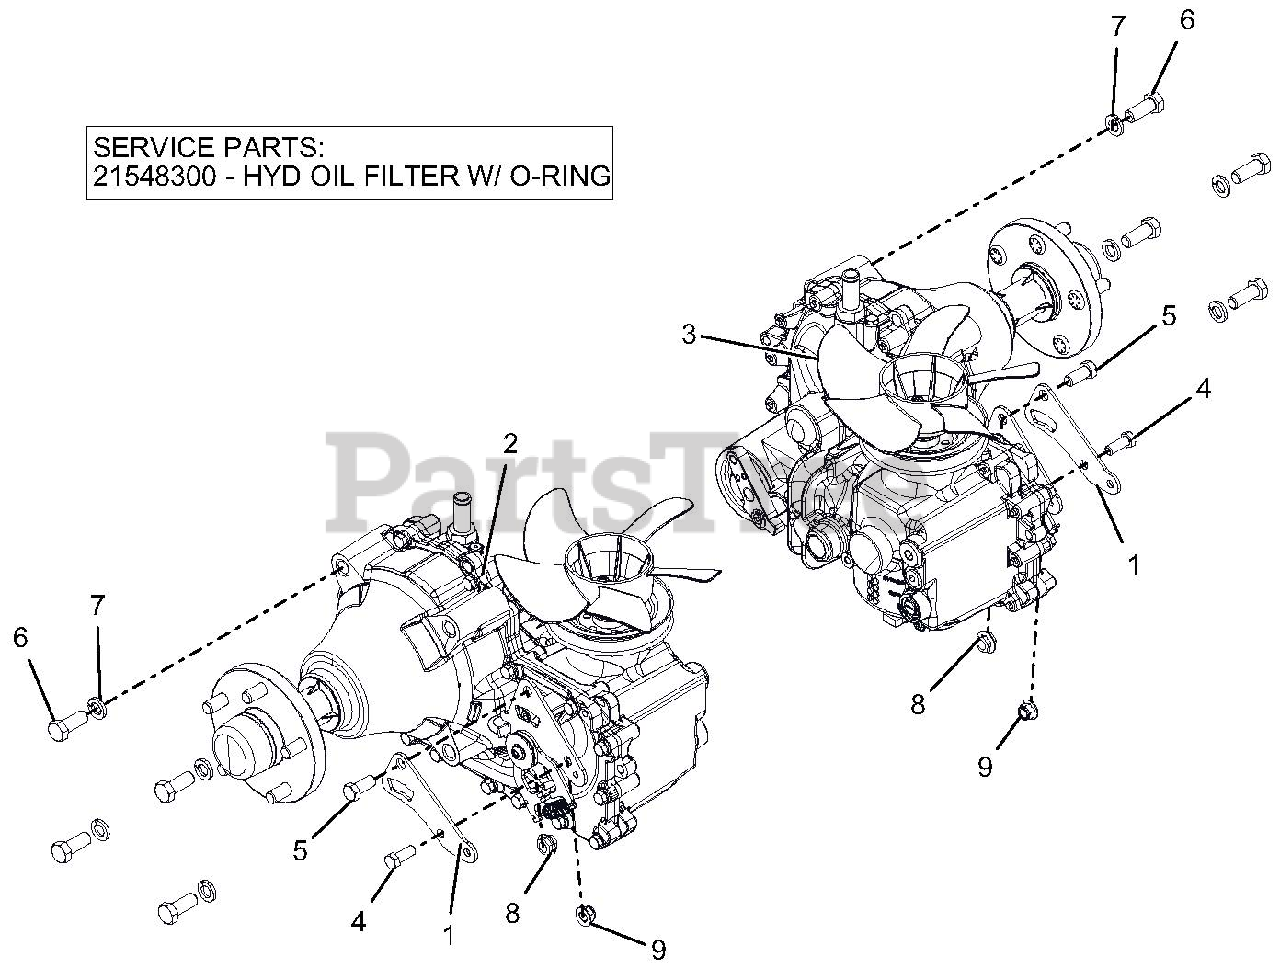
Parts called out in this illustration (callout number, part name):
1	CONTROL MTG BRACKET - BLACK
2	TRANS, RH HG ZT-5400
3	TRANS, LH HG ZT-5400
4	@BLT-HEX .38-16X1.00 GR5 YWZC
5	@BLT-HEX .44-14X1.00 GR5 YWZC
6	@BLT-HEX .50-13X1.25 GR5 YWZC
7	@WSHR-LK .50X.125 REG YWZC
8	@NUT-LK-NYL-FLG .44-14 YWZC
9	@NUT-LK-NYL-FLG .38-16 YWZC
10	FILTER,HYD OIL W/ORING ZT-54OO
